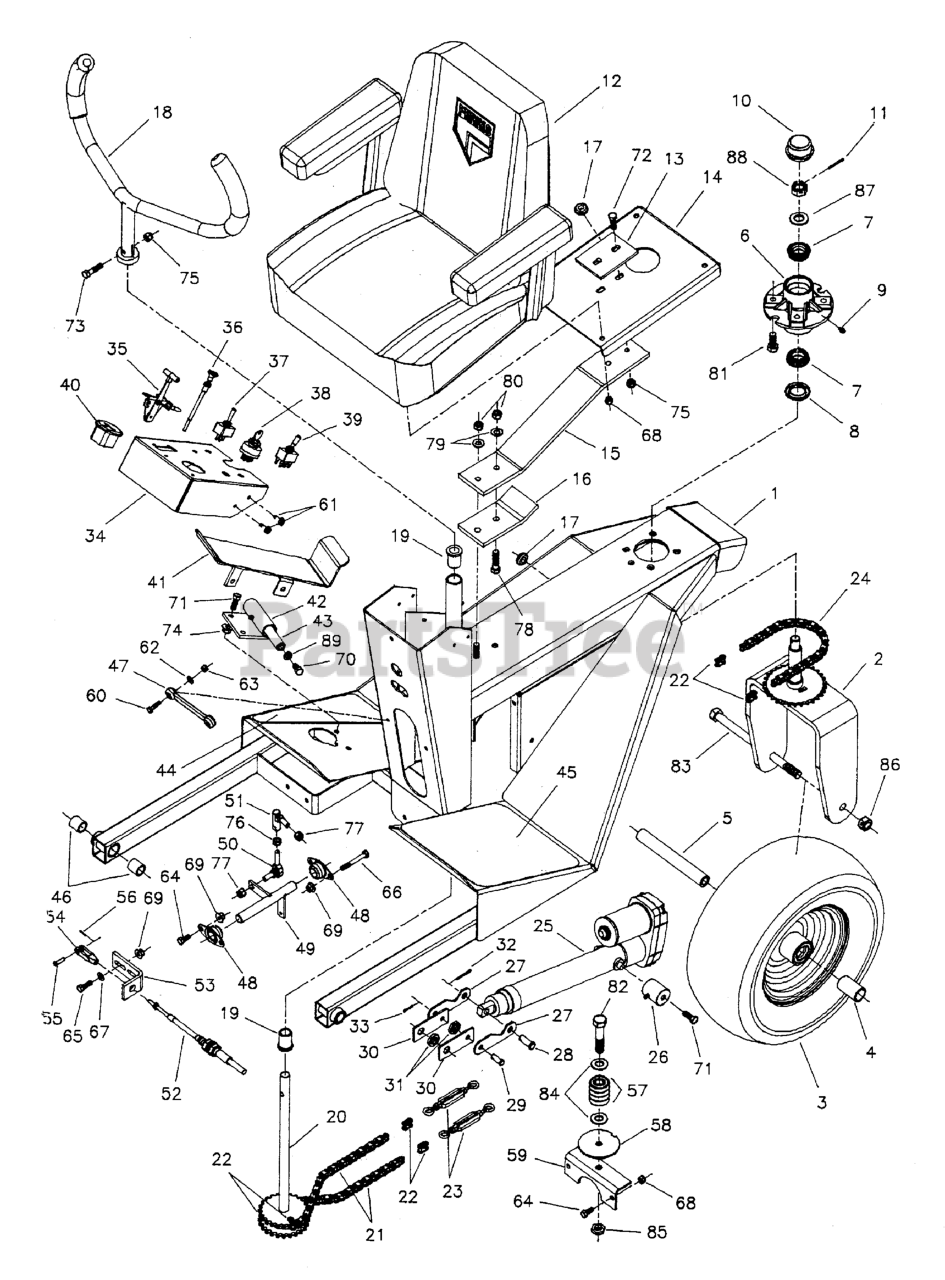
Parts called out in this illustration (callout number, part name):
1	TRAILER WELDMENT
2	MOUNT, Steering Tire
3	WHEEL & TIRE ASSEMBLY, 18 x 7.5 x 8, White, Complete
4	SPACER, 1.01 X 1.25 X 2.06
5	STEERING TIRE AXLE
6	HUB, Steering
7	BEARING, Tapered Roller
8	SEAL, GREASE
9	GREASE FITTING
10	CAP
11	PIN, COTTER, 1/8 X 1-1/4
13	SUPPORT, Seat Plate
14	PLATE, Seat
15	SEAT SPRING
16	SUPPORT, Seat Spring
17	GROMMET, 1/2"
18	STEERING HANDLE ASSEMBLY
19	BUSHING, Flange
20	SHAFT, Steering Sprocket
21	CHAIN, #40 Roller, 31 Links
22	CONNECTOR, #40 Chain Link
23	TURNBUCKLE
24	CHAIN, #40 Roller, 35 Links
25	ELECTRIC ACTUATOR
26	ACTUATOR MOUNT
27	ACTUATOR LINK, Lower
28	PIN, Clevis
29	CLEVIS PIN, 3/8 x 1
30	ACTUATOR LINK, Upper
31	SPACER, .63 x 1.06 x .23
32	PIN, COTTER, 1/8 X 1-1/4
33	PIN, 3/32 X 0.750, COT, ZINC/CLEAR
35	CABLE, Throttle, 54"
36	CABLE, CHOKE CONTROL, 45
37	SWITCH, Actuator
38	SWITCH, IGNITION, 6 POST
39	SWITCH, Electric Clutch
40	HOUR METER
41	FOOT CONTROL PEDAL
41	SAFETY WALK
42	FOOT PEDAL PIVOT MOUNT, Complete
43	SHAFT, Pedal Pivot
44	SAFETY WALK
45	SAFETY WALK
46	BUSHING, Plastic
47	RUBBER STRAP
48	BEARING, Flange
49	BELL CRANK
50	BALL JOINT, 3/8-24 Male, Studded
51	BALL JOINT, 3/8" Female Studded
52	CABLE, Speed Control
53	CABLE BRACKET
55	CLEVIS PIN, 1/4 x 1
56	COTTER PIN, 1/16" x 1/2"
57	BEARING, Roller
58	WASHER, Chain
59	MOUNT, Chain Roller
60	BOLT, 1/4-20 X 1" GD5 CZ
61	BOLT, Self-Tapping, 1/4-20 x 3/4
62	WASHER, 1/4 SAE
63	NUT, 1/4-20 HEX NYLON LOCK
64	BOLT, 5/16-18 X 3/4 GD5
65	BOLT, 5/16-18 X 1 GD5 YZ
66	BOLT, 5/16-18 x 2-1/2
67	WASHER, 5/16" SAE
68	NUT, 5/16-18 Hex Nylon Lock
69	NUT, 5/16-18 HEX SERRATED FLANGE (LARGE)
70	BOLT, 3/8-16 X 3/4" GD5 CZ
71	BOLT, 3/8-16 X 1" GD5 CZ
72	BOLT, 3/8-16 X 1-1/4" GD5 CZ
73	BOLT, 3/8-16 X 1-1/2" GD5 CZ
74	NUT, 3/8-16 Hex Serrated Flange
75	NUT, 3/8-16 HEX NYLON LOCK
76	NUT, 3/8-24 Hex
77	NUT, 3/8-24 Hex Nylon Lock
78	BOLT, 7/16-20 x 1-3/4
79	WASHER, 7/16" SAE
80	NUT, 7/16-20 Hex Nylon Lock
81	BOLT, 1/2-20 X 1-1/4" GD5 CZ
82	BOLT, 5/8-11 x 3" GD5 CZ
83	BOLT, 5/8-11 x 9-1/2
84	WASHER, 5/8" SAE
85	NUT, 5/8-11 Hex Jam Nylon Lock
86	NUT, 5/8-11 Hex Side Lock
87	WASHER, 3/4 SAE
88	NUT, 3/4-16 Hex Slotted
